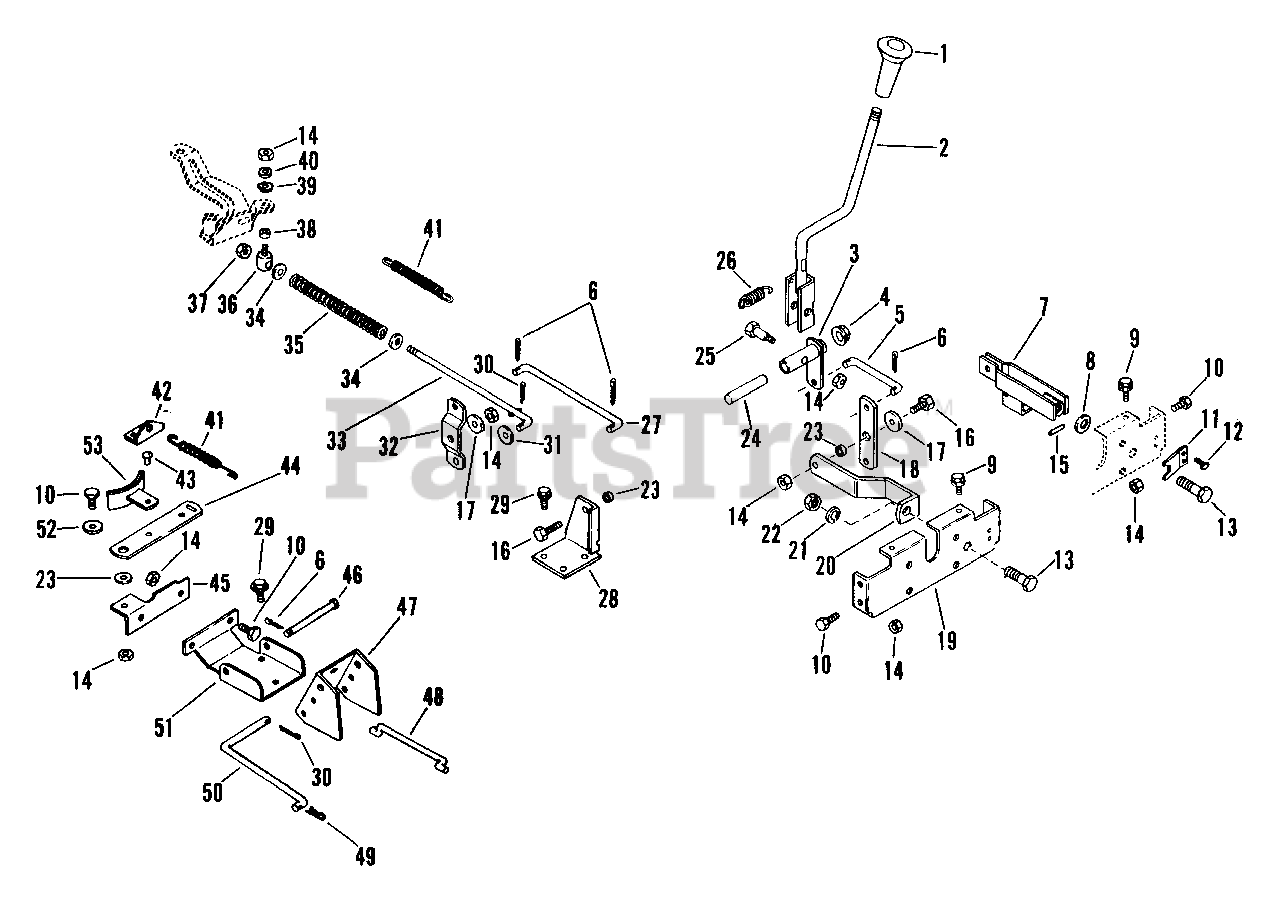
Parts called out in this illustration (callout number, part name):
2	MOWER CLUTCH LEVER
3	CLUTCH ARM
4	FLANGE BUSHING
5	LINK
6	PIN-COTR .09X.75 PL
7	ADJUSTMENT YOKE
8	WSHR-FL-STL .505X1.000X.062
9	SCR-TAP .250-20X.50 HXSLHDPL
10	BLT-HEX .31-18X.63 PL GR 2
11	LOCK SPRING
12	SCR-TAP 10-24X.25 CRSLPH PL 1A
13	CAP SCREW
13	BLT-HEX .50-13X1.25 PL GR2
14	NUT-LK .312-18 GR A PL
15	PIN-ROLL .188X1.00
16	BLT-HEX .31-18X.88 PL GR2
17	WSHR-FL-STL .344X1.125X.063PL
18	CLUTCH LINK
19	MOWER ADJUSTMENT BRACKET
20	FRONT ANCHOR
21	WSHR-LK .500X.151 HVY PL
22	NUT .50-13 PL
23	SPACER BUSHING .5 X .32 X .163
25	SHOULDER BOLT .436 X .912
26	SG-TENS .092X.69X1.75 WLD 54
27	CLUTCH ROD
28	DECK PIVOT BRACKET
29	SCR-TAP .312-18X.50 HWH PL TR
30	PIN-COTR .12X.75 PL
31	WSHR-FL-STL.344X.688X.065PL
32	ARM
33	CLUTCH ROD
34	WSHR-FL-STL .38X.875X.083 PL
35	SG-COMP .148X.68X6.5 WLD 90
36	ROD PIVOT
37	NUT-LK-CTR .375-16 GR A PL
38	SPACER BUSHING .5 X .32 X .21
39	WAVE WASHER .531X.781X.125FH
40	WSHR-FL-STL .323X.625X.062 PL
41	SG-TENS .072X.51X5.31 WLD 25
42	BRAKE CLIP
43	RVT .25X.50 RH ST
44	MOWER BRAKE LEVER
45	BRAKE BRACKET
46	PIN-CLEV .309X3.50 SP
47	MOWER ENGAGING ARM
48	MOWER BRAKE LINK
49	PIN-HAIR INT .08X.38X1.42 YWZC
50	MOWER ENGAGEMENT LINK
51	PIVOT BRACKET
52	WSHR-FL-STL .328X1.0X.094
53	BLADE BRAKE
54	SCR-TAP .250-20X.37 HWH PL TR
